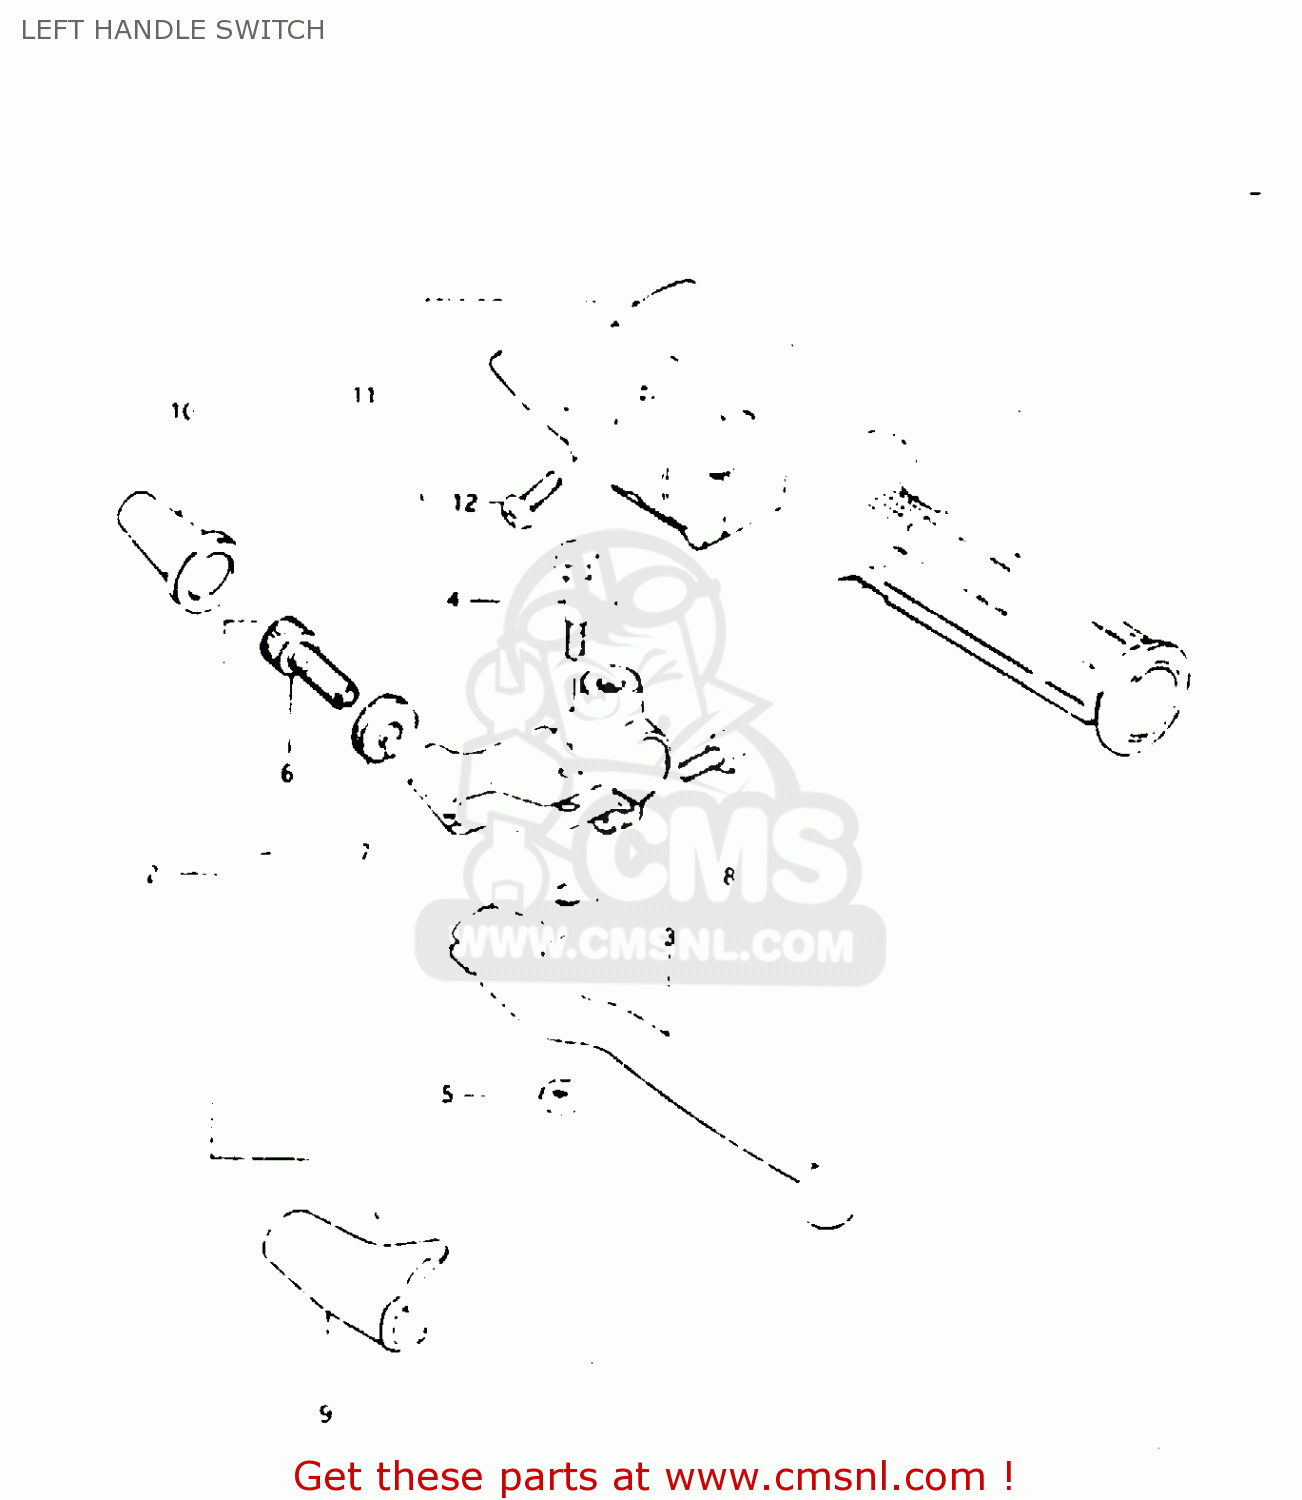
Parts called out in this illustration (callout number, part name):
1	GRIP,LEFT
2	LEVER ASSEMBLY
3	LEVER,CLUTCH
4	BOLT,LEVER
5	NUT 6MM
6	ADJUSTER,CABLE
7	NUT,CABLE ADJUSTER
8	BOLT,CLUTCH LEVER HOLDER
9	COVER,CLUTCH LEVER
10	BOOT,CLUTCH CABLE
11	SWITCH ASSY, HANDLE LH
12	SCREW
